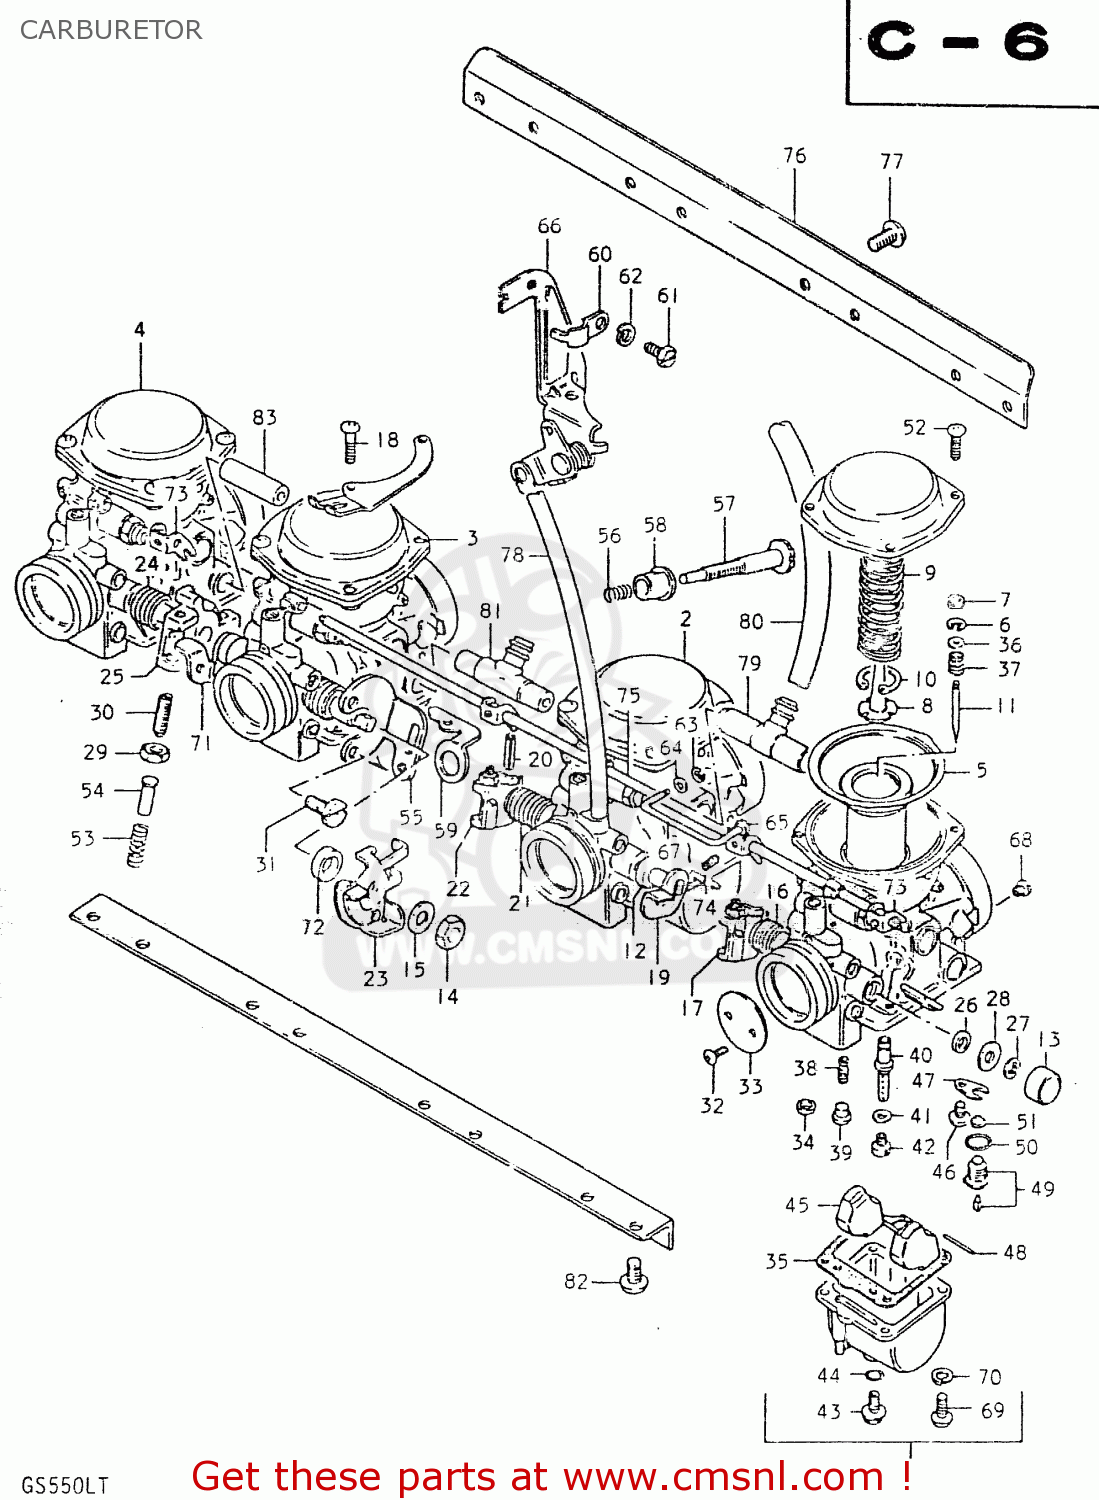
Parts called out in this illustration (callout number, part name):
1	CARBURETOR ASSEMBLY,NO.1 (A
2	CARBURETOR ASSEMBLY
3	CARBURETOR ASSEMBLY
4	CARBURETOR ASSEMBLY
5	DIAPHRAGM ASSEMBLY
6	CLIP,NEEDLE
7	RING
8	HOLDER,GUIDE
9	SPRING
10	E RING
11	NEEDLE JET
12	GASKET,THROTTLE SHAFT (NAS)
13	CAP
14	NUT
15	WASHER
16	SPRING,THROTTLE SHAFT
17	SHAFT,THROTTLE
18	SCREW
19	SHAFT,THROTTLE
20	PIN,THROTTLE SHAFT
21	SPRING,THROTTLE SHAFT
22	LEVER,THROTTLE SHAFT
23	LEVER ASSEMBLY,THROTTLE
24	SPRING,THROTTLE SHAFT
25	SHAFT,THROTTLE
26	SEAL
27	E RING
28	GASKET,THROTTLE SHAFT (NAS)
29	NUT
30	SCREW
31	SCREW,THROTTLE ADJUST B
32	SCREW
33	VALVE,THROTTLE
34	GASKET (NAS)
35	GASKET,FLOAT CHAMBER (NAS)
36	WASHER
37	SPRING
38	JET,PILOT
39	PLUG,NEEDLE JET
40	JET,NEEDLE
41	WASHER,NEEDLE NOZZLE
42	JET,MAIN(92.5)
43	PLUG,DRAIN
44	GASKET (NAS)
45	FLOAT
46	SCREW
47	PLATE
48	PIN,FLOAT
49	VALVE ASSEMBLY,NEEDLE
50	O-RING,NEEDLE VALVE
51	FILTER
52	SCREW
53	SPRING,THROTTLE SCREW
54	PIN,THROTTLE LEVER
55	BRACKET,THROTTLE ADJUST
56	SPRING
57	SCREW
58	BUSH
59	BRACKET,THROTTLE ADJUST
60	BRACKET,STARTER
61	BOLT
62	LOCK WASHER
63	CAP,LEVER
64	SEAT,SPRING
65	LEVER ASSY
66	BRACKET
67	ROD,STARTER LEVER
68	JET,AIR(150)
69	SCREW
70	LOCK WASHER
71	SHAFT,THROTTLE
72	WASHER
73	LEVER
74	SCREW
75	SHAFT,STARTER
76	BRACKET
77	SCREW
78	HOSE
79	NIPPLE
80	HOSE
81	NIPPLE,CARBURETOR
82	SCREW 6X12
83	NIPPLE
